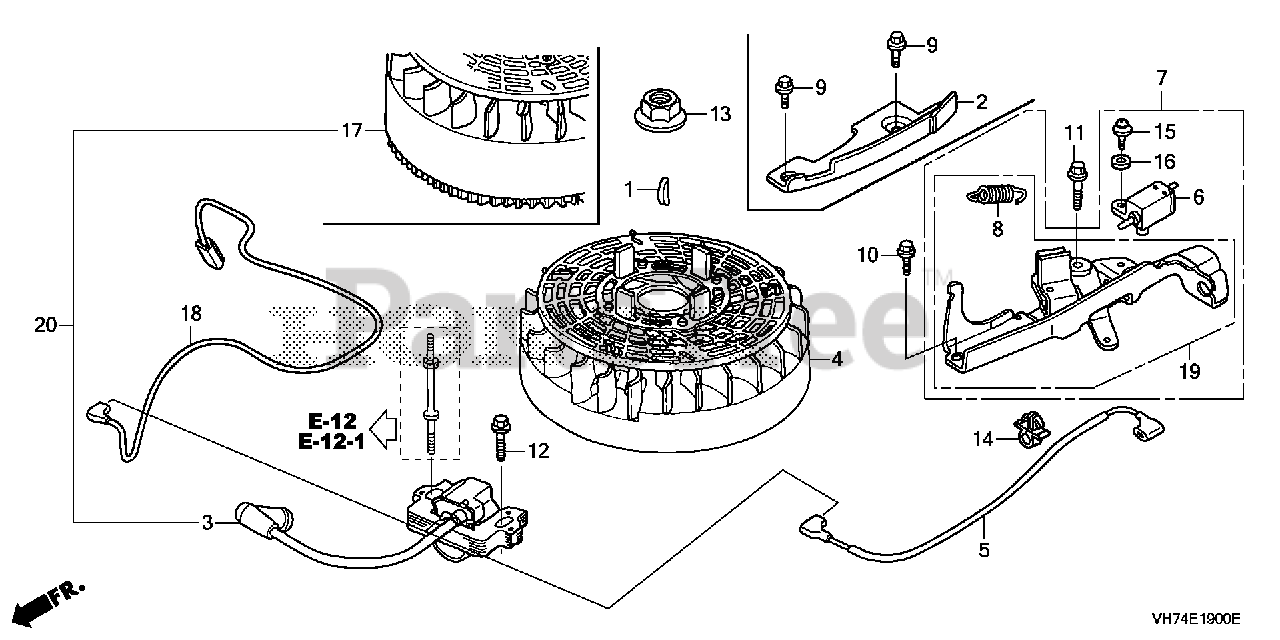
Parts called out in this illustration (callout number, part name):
1	KEY, SPECIAL WOODRUFF (25X18)
2	PLATE, SIDE
3	COIL ASSY., IGNITION (PHELON) (USE FOR F/W OF PHELON)
3	COIL ASSY., IGNITION (PHELON)
3	COIL ASSY., IGNITION (USE FOR F/W OF TEC) (TEC)
9	BOLT, FLANGE (6X12) (CT200)
12	BOLT, FLANGE (6X20) (CT200)
12	BOLT, FLANGE (6X23) (CT200)
13	NUT, FLANGE (14MM)
17	FLYWHEEL ASSY. (PHELON) (USE FOR IGN. COIL OF PHELON) (NA USE ALT:31105-Z0Y-932)
18	WIRE, STOP SWITCH
